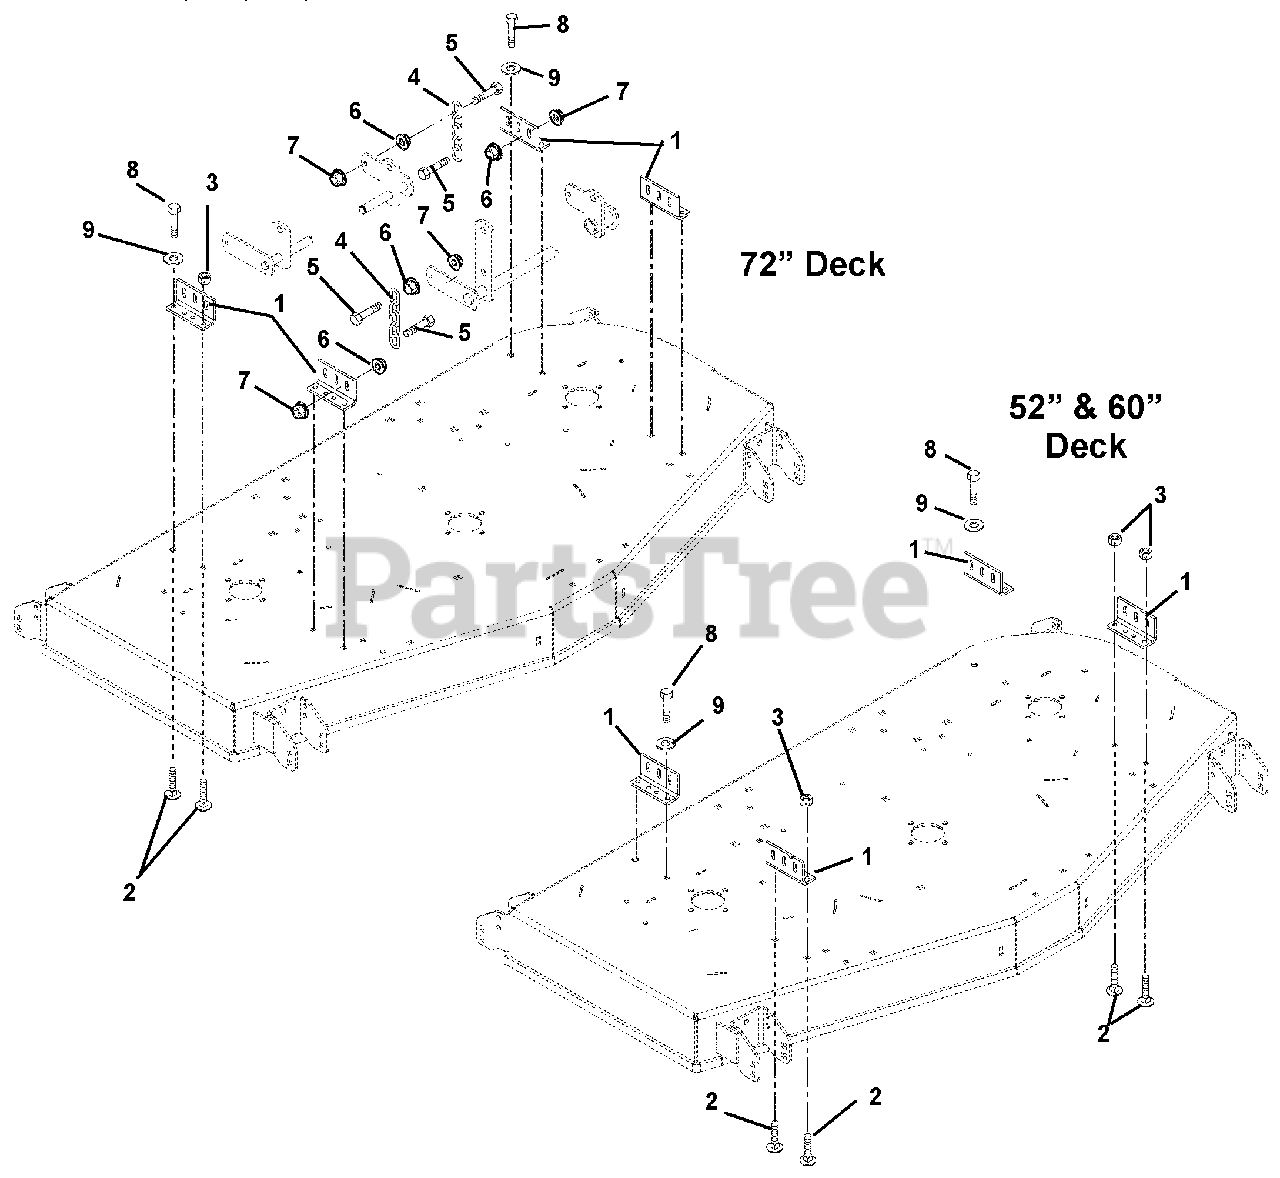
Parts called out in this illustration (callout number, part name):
1	Bracket, Mower Mounting
2	Bolt, Round Head Square Neck .38-16 x 1.00 Grade 5 (321, 316, 317)
3	Nut, Locking-Top-Flange .38-16 (321, 316, 317)
4	Chain, Link
5	Bolt, Hex M12-1.75 Grade 5
6	Nut, Spin Lock Flange M12-1.75
7	Nut-Locking-Top-Flange M12-1.75
8	Bolt, Hex .38-16 x 1.00 (316, 317, 321)
9	Washer, Lock .38 x .094 (316, 317, 321)
